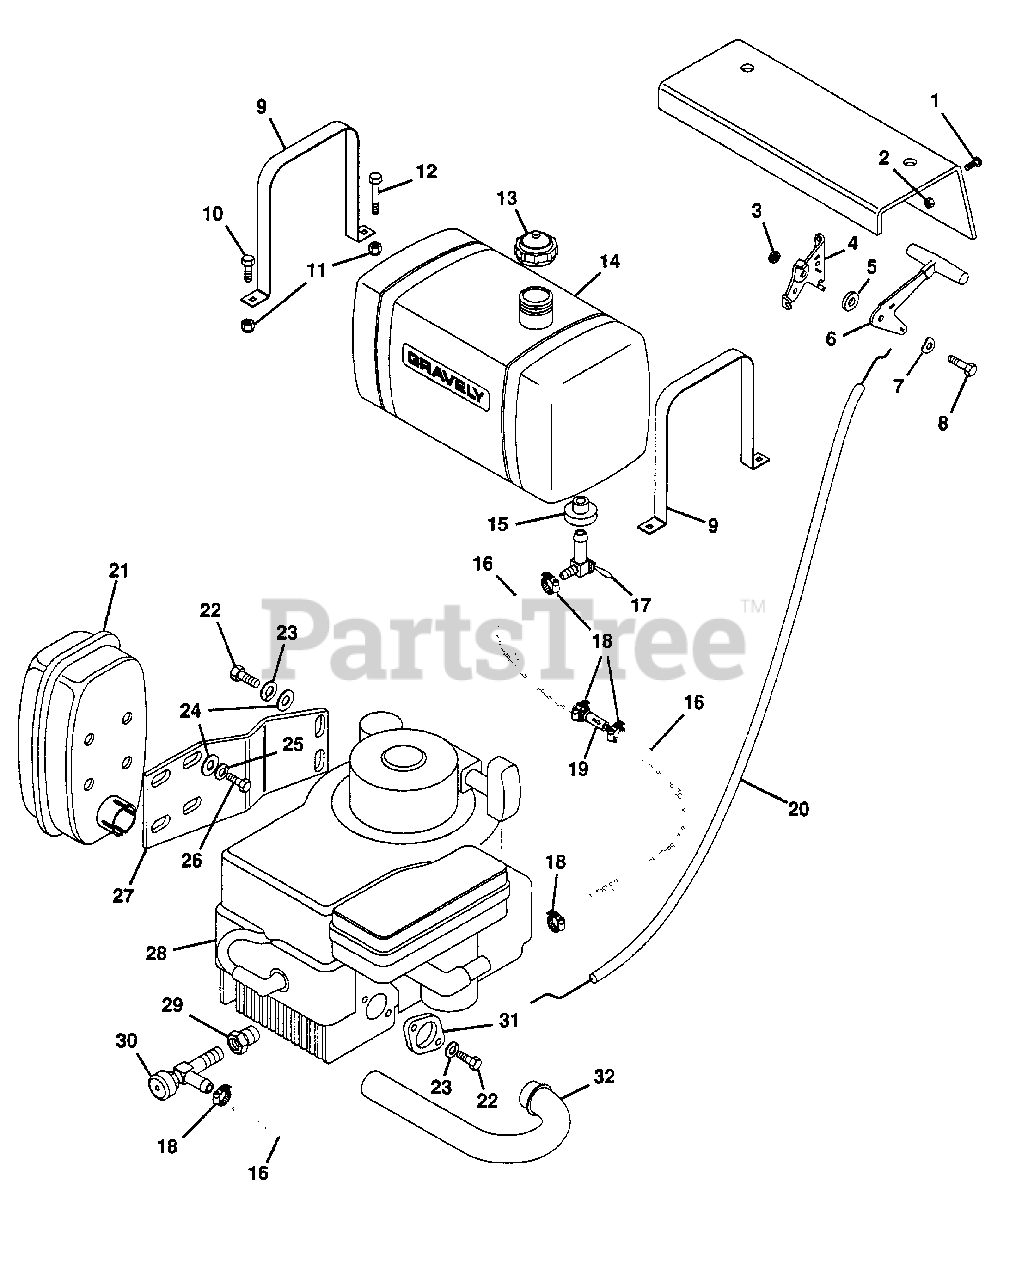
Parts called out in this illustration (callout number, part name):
1	SCREW, MACH. 10-32X.50 PHD
2	NUT, LOCK 10-32
3	NUT, LOCK 1/4-28
4	BRACKET, MOUNTING L.H.
5	WASHER, FRICTION
6	ASSEMBLY, KNOB AND LEVER
7	WASHER, SPRING
8	BOLT, HEX 1/4-28X.75
9	STRAP, FUEL TANK
10	BOLT, HEX 1/4-20X.625
11	NUT, LOCK 1/4-20
12	BOLT, HEX 1/4-20X1.75
13	CAP, FUEL TANK
14	TANK, FUEL
15	BUSHING, FLANGE
16	LINE, FUEL
17	VALVE, BALL SHUT-OFF
18	CLAMP, HOSE
20	ASSEMBLY, THROTTLE CONDUIT
21	MUFFLER
22	BOLT, HEX 5/16-18X.75
23	WASHER, LOCK 5/16 REG.
24	WASHER, FLAT .344X.688X.065
25	WASHER, LOCK 1/4 REG.
26	BOLT, HEX 1/4-20X.75
27	PLATE, EXHAUST
28	ENGINE, 12 HP B&S
29	ADAPTOR, OIL DRAIN
30	COCK, OIL DRAIN
31	FLANGE, MUFFLER
32	TUBE, EXHAUST
